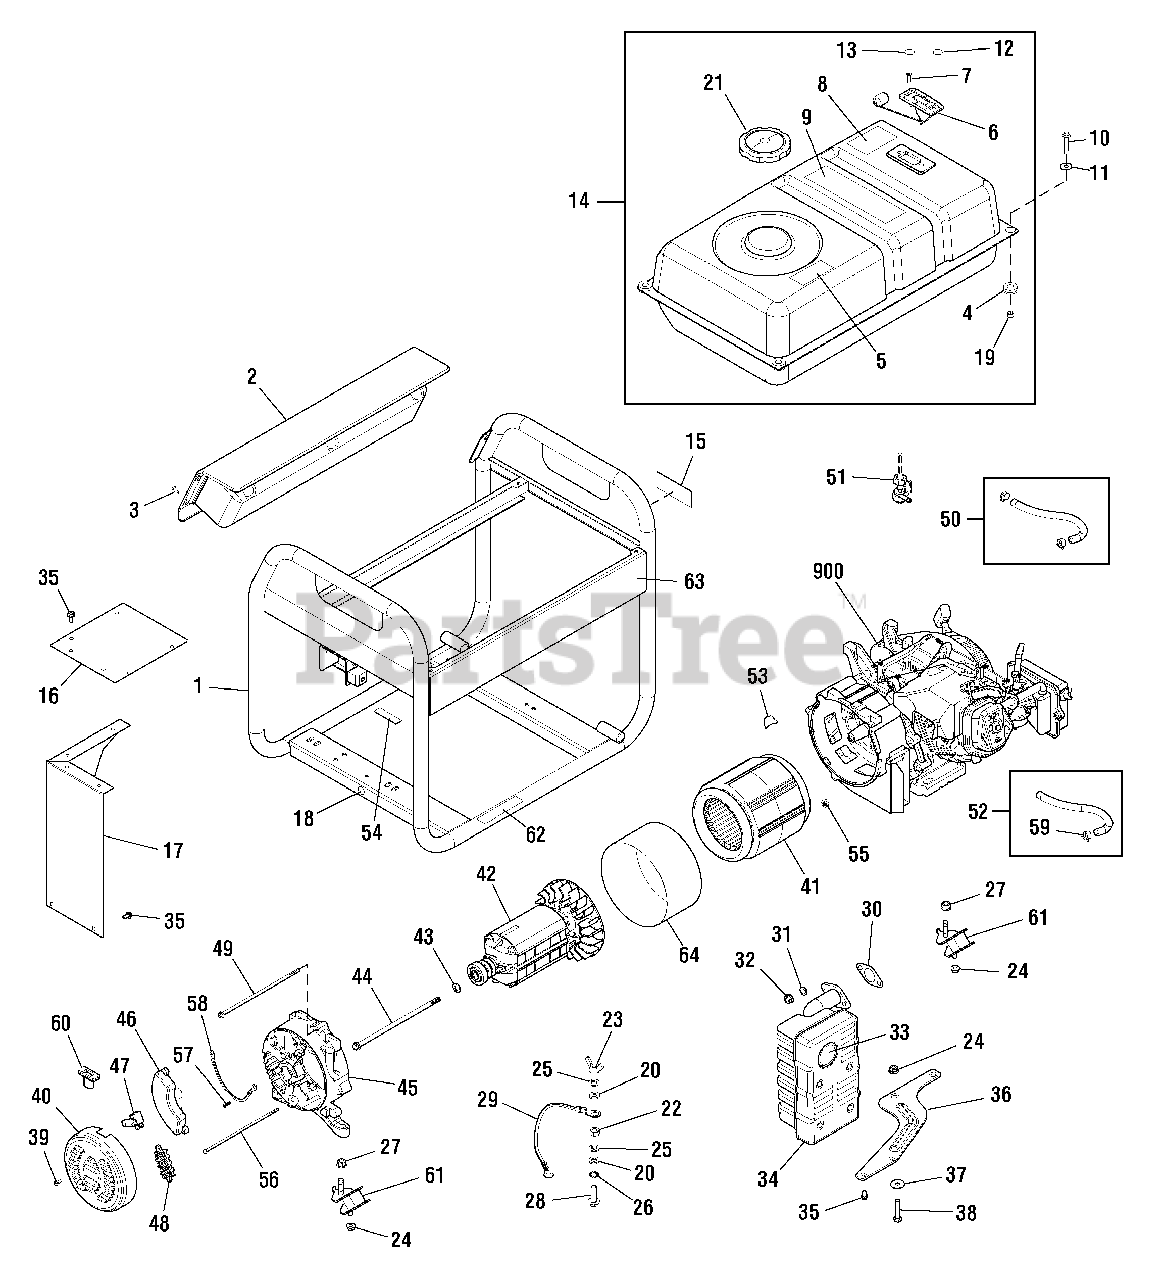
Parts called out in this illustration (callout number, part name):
2	PANEL-CONTROL
20	* WASHER, Flat, M6
22	* NUT, Hex, M6
24	* NUT, Flange Lock, M8
25	* WASHER, Lock, M6
26	* WASHER, Ext, Shakeproof, M6
27	* NUT, Flange Lock, M10
28	* CAPSCREW, Hex Head, M6-1.0 x 25
30	GASKET
31	* WASHER, Lock, M8
32	* NUT, Hex, M8 1.25
35	SCREW
36	BRACKET-MUFFLER
37	* WASHER, Flat, M8
38	* CAPSCREW, Hex Head, M8-1.25 x 40
43	WASHER
45	CARRIER-BEARING
46	VOLTAGE REGULATOR
50	KIT-FUEL HOSE (cut to fit)
61	MOUNT-VIBRATION
900	** ENGINE
